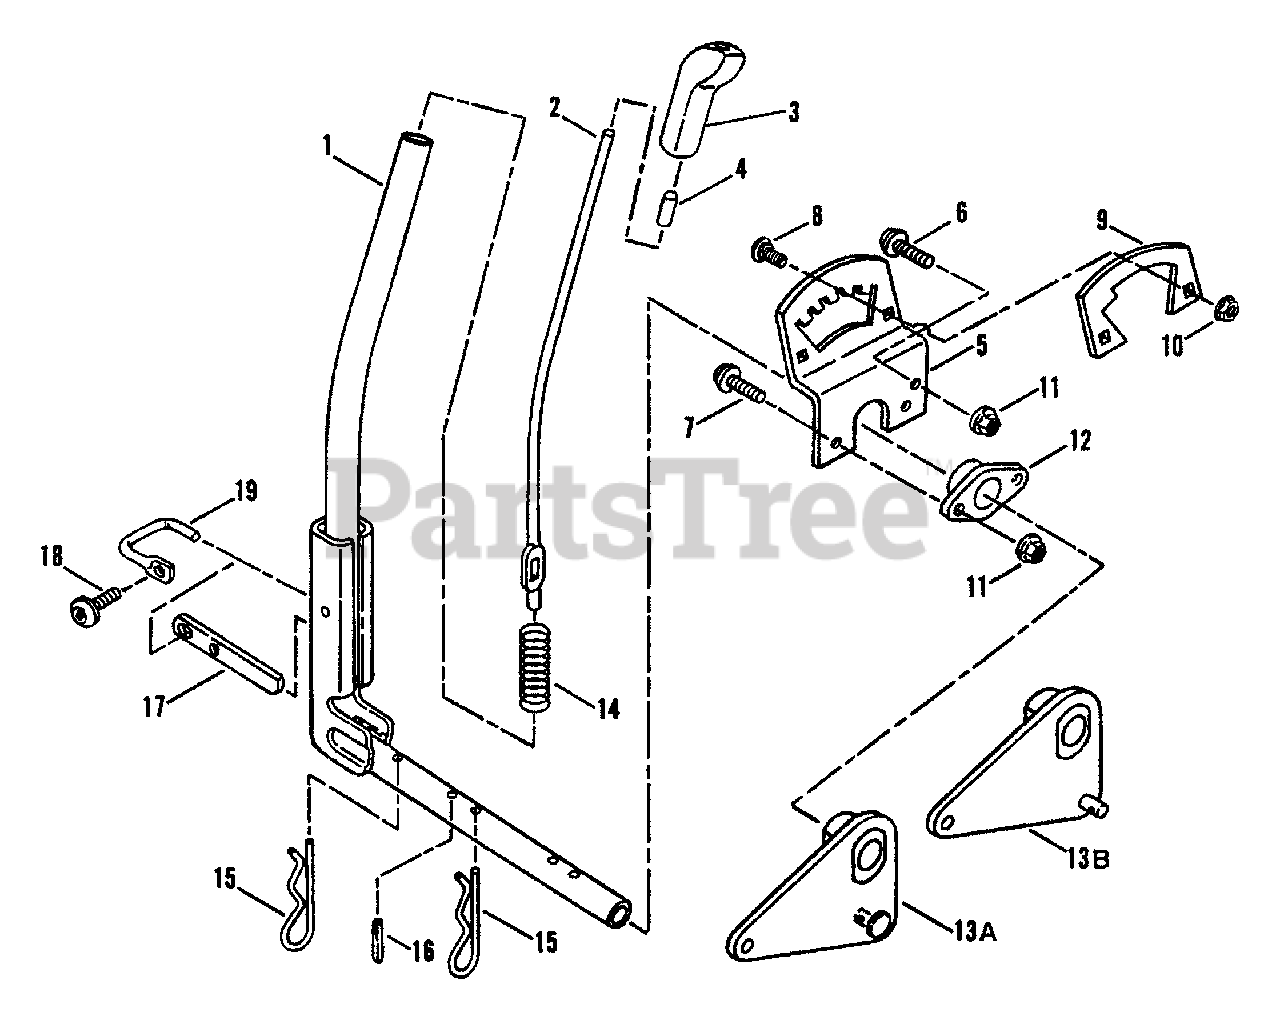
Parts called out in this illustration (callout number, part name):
1	LEVER, Implement Lift (33" Decks)
1	LEVER, Implement Lift (38" Decks)
2	ROD, Lift Lever
3	KNOB, Lift Lever
4	CAP, Lift Lever Rod
5	QUADRANT, Lift Lever
6	SCREW, 5/16-18 x 5/8" Truss Head (Torx)
7	SCREW, 5/16-18 x 7/8" Truss Head (Torx)
8	BOLT, 1/4-20 x 1/2" Short Neck Carriage, Grade 5
9	DETENT, High Cut Lockout
10	NUT, 1/4-20 Hex Flange Lock, Grade 5
11	NUT, 5/16-18 Hex Flange Lock, Grade 5
12	PIVOT, Lift Lever
13A	BELL CRANK, Lift Lever (33" Decks)
13B	BELL CRANK, Lift Lever (38" Decks)
15	PIN, Hair, 5/32 x 2 5/8"
16	PIN, Dowel, 1/4 x 1 1/8"
17	DETENT, Latch
18	SCREW, 1/4-20 x 5/8" Truss Head (Torx)
19	LATCH, Pivot
